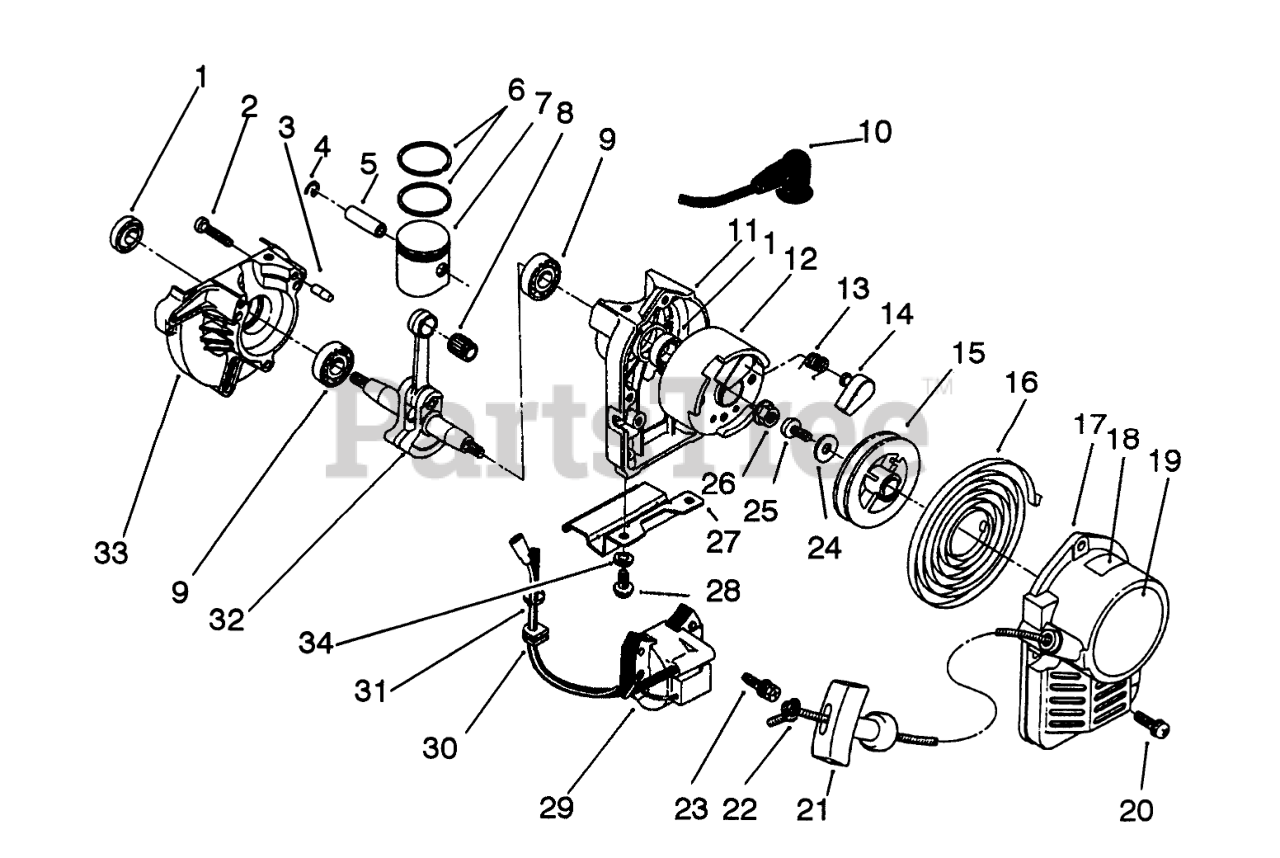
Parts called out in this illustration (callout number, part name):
1	OIL SEAL
2	Screw
4	PISTON PIN CLIP
5	PISTON PIN
6	SEAT VALVE
7	Piston Assembly(Incl. Ref.# 5)
8	NEEDLE BEARING
9	BEARING
10	CAP-PLUG
11	STARTER CASE
12	Rotor Assembly(Incl. Ref.# 13-14)
13	RETURN SPRING
14	RATCHET
16	SPRING
17	STARTER CASE
18	DECAL-SURFACE, HOT
19	Decal-Toro
20	SCREW & WASHER
21	Knob-Starter
22	Rope-Recoil
23	BOLT & WASHER
24	Washer
25	SCREW
27	STAND SUPPORT
28	M6 X 1 X 1/2 MWH SCREW
29	IGNITION COIL
30	GROMMET
32	CRANKSHAFT ASSEMBLY
33	DRIVE CASE
34	WASHER-LOCK
